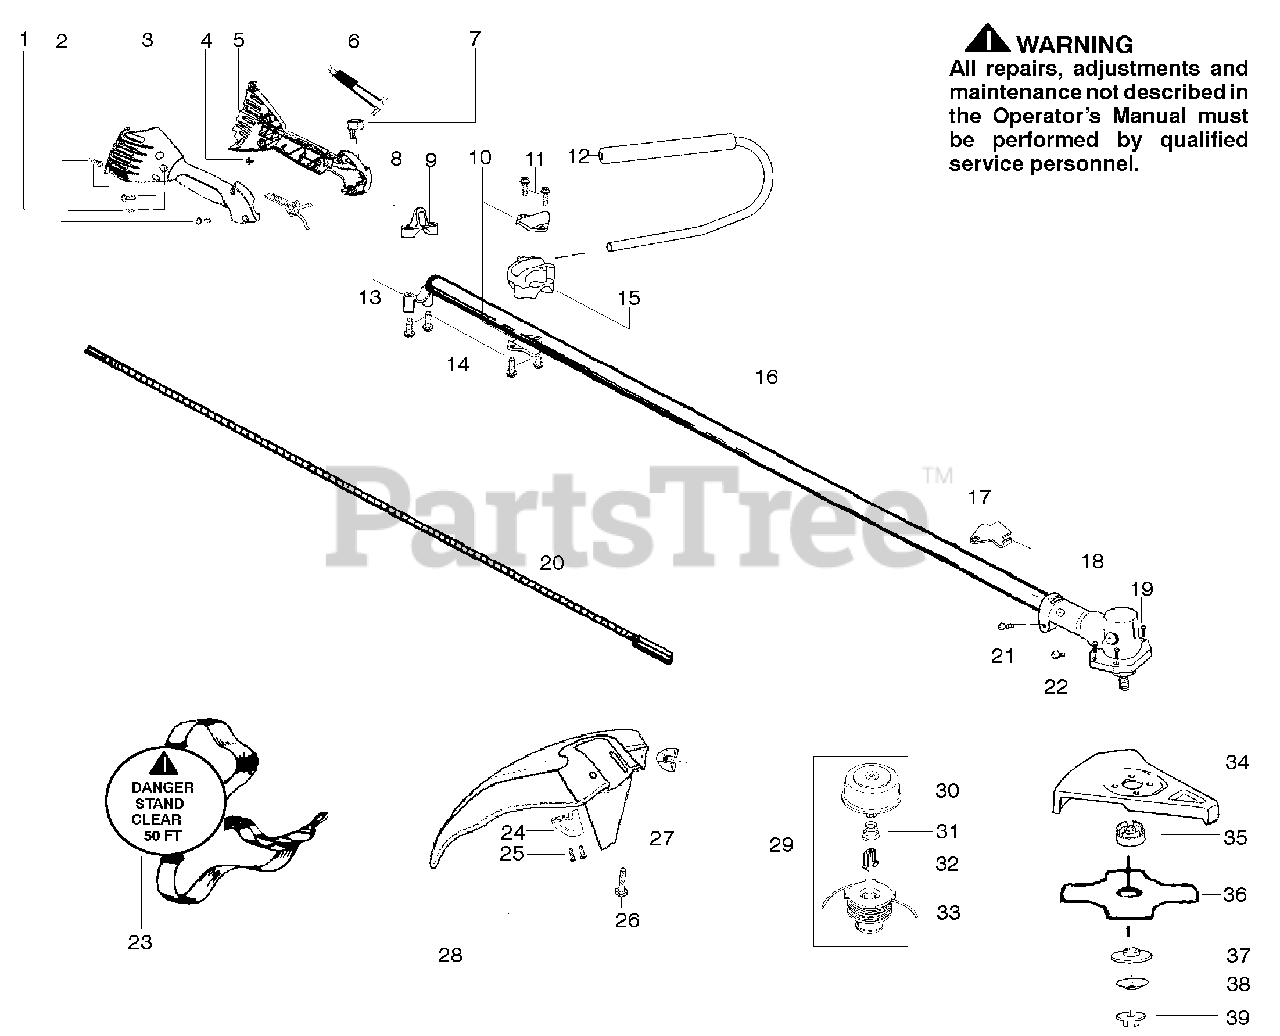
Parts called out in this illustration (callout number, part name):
1	Screw-alignment
3	Hsg.-Throttle-right
4	Screw-Cable Ret.
5	Hsg.-Throttle-left
8	Trigger-Throttle
9	Clamp-Harness (upper)
10	Clamp-Bracket
12	Kit-Handlebar Assy.
13	Clamp-Harness (lower)
15	Clamp-Handlebar
16	Kit-Shaft Assy.
17	Bracket-Shield
23	Shoulder Strap
27	Wingnut
28	Kit-Shield Assy.
29	Accy-Cutting Head
33	Accy-Wound Spool
34	Kit-Metal Shield
36	Accy.-Weed Blade
38	Washer-Belleville
